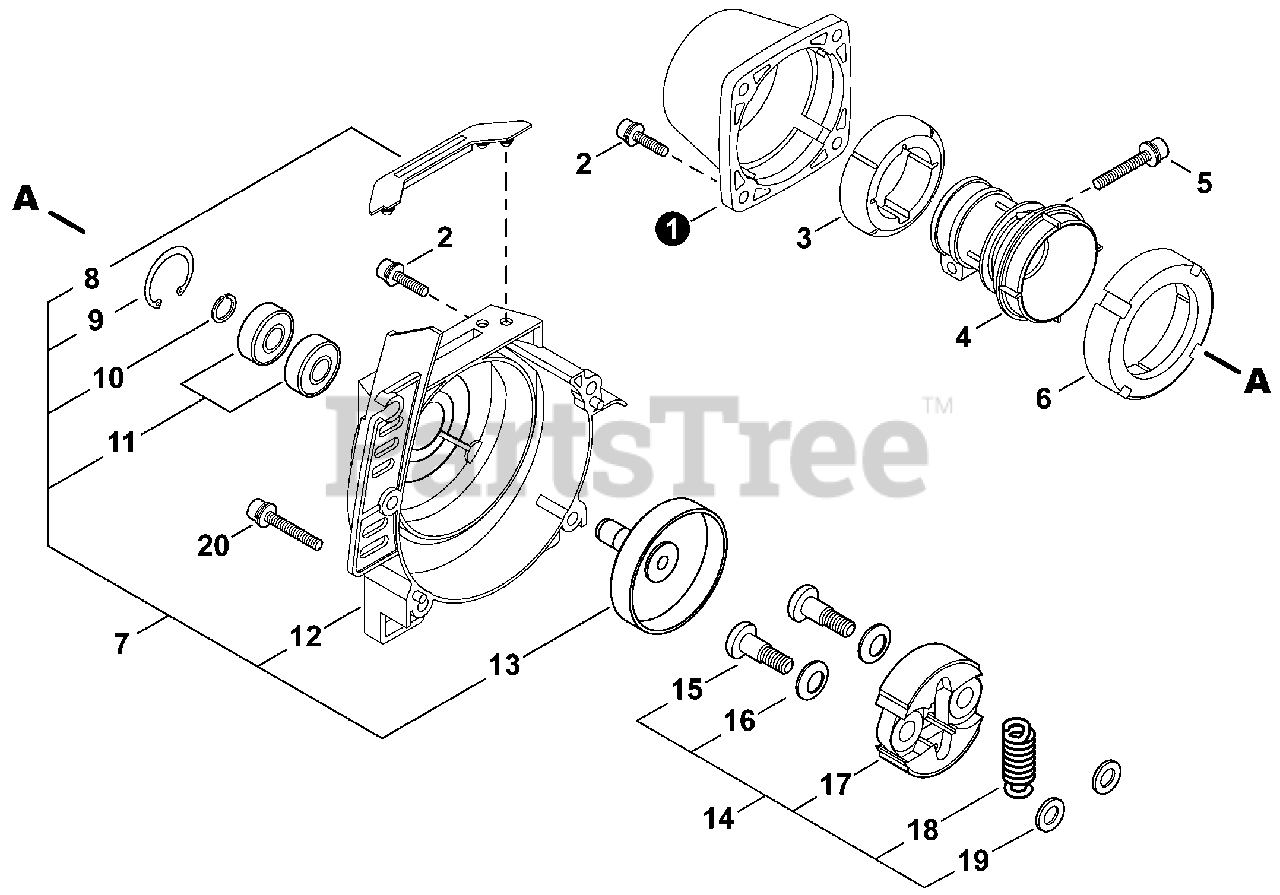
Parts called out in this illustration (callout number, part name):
1	COVER, AV CUSHION (RED)
2	BOLT M5×16
3	CUSHION, FRONT
4	CUSHION, AV
5	BOLT M5×25
6	HOLDER, REAR CUSHION
7	COVER ASSY, FAN
8	CUSHION
9	RING, SNAP Ø26
10	RING, SNAP Ø10
11	BEARING, BALL 6000ZZ
12	COVER, FAN
13	DRUM, CLUTCH
14	CLUTCH ASSY
15	BOLT, CLUTCH
16	WASHER, SPRING
17	SHOE, CLUTCH
18	SPRING, CLUTCH
19	WASHER 6MM
20	BOLT M5×45
